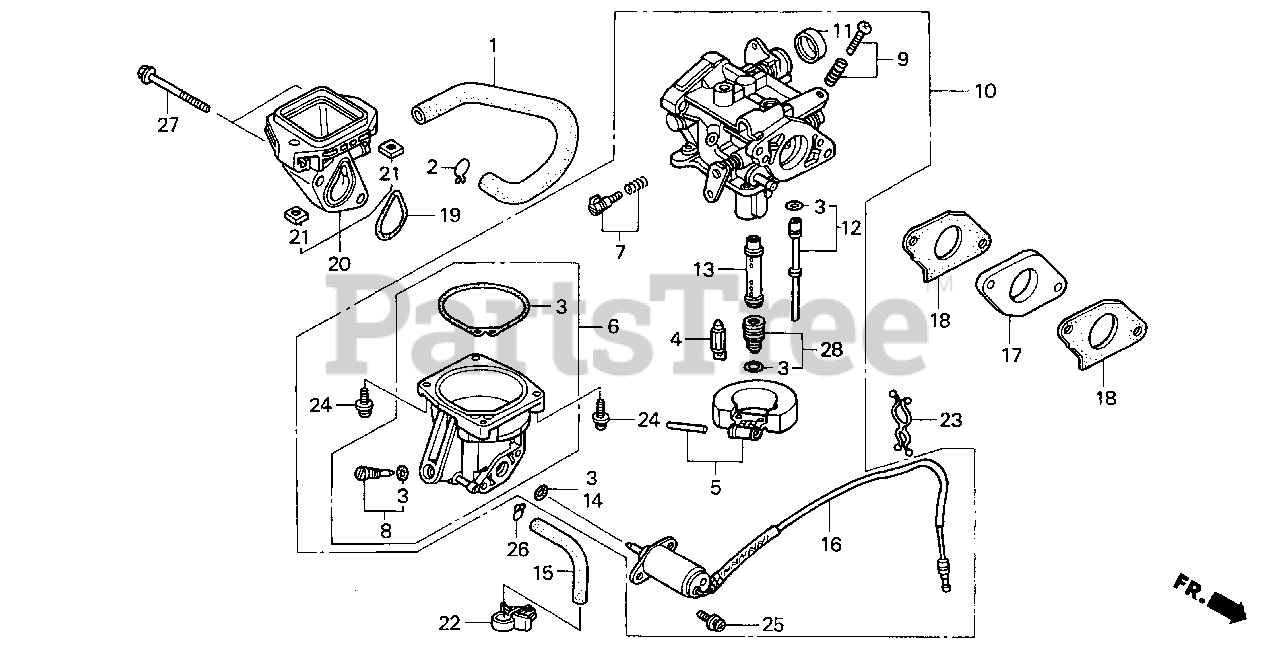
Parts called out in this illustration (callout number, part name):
1	TUBE, BREATHER
2	CLIP, BREATHER TUBE
3	GASKET SET
4	VALVE SET, FLOAT
5	FLOAT SET
6	CHAMBER SET, FLOAT
7	SCREW SET
8	SCREW SET, DRAIN
9	SCREW SET
10	CARBURETOR ASSY. (BG21M A)
11	CAP, CHOKE LEVER DUST
12	JET SET (#52)
13	NOZZLE, MAIN
14	O-RING (5.8X1.9)
15	TUBE, DRAIN
16	VALVE ASSY., SOLENOID
17	INSULATOR, CARBURETOR
18	GASKET, CARBURETOR
19	GASKET, AIR CLEANER
20	ELBOW, AIR CLEANER
21	NUT, INSERT (6MM)
22	CLIP B, CABLE
23	CLIP, PURSE LOCK
24	SCREW-WASHER (4X14)
25	SCREW-WASHER (5X12)
26	CLIP, TUBE (B8)
27	BOLT, FLANGE (6X120)
28	JET SET, MAIN (#90)
28	JET SET, MAIN (#92)
28	JET SET, MAIN (#95)
